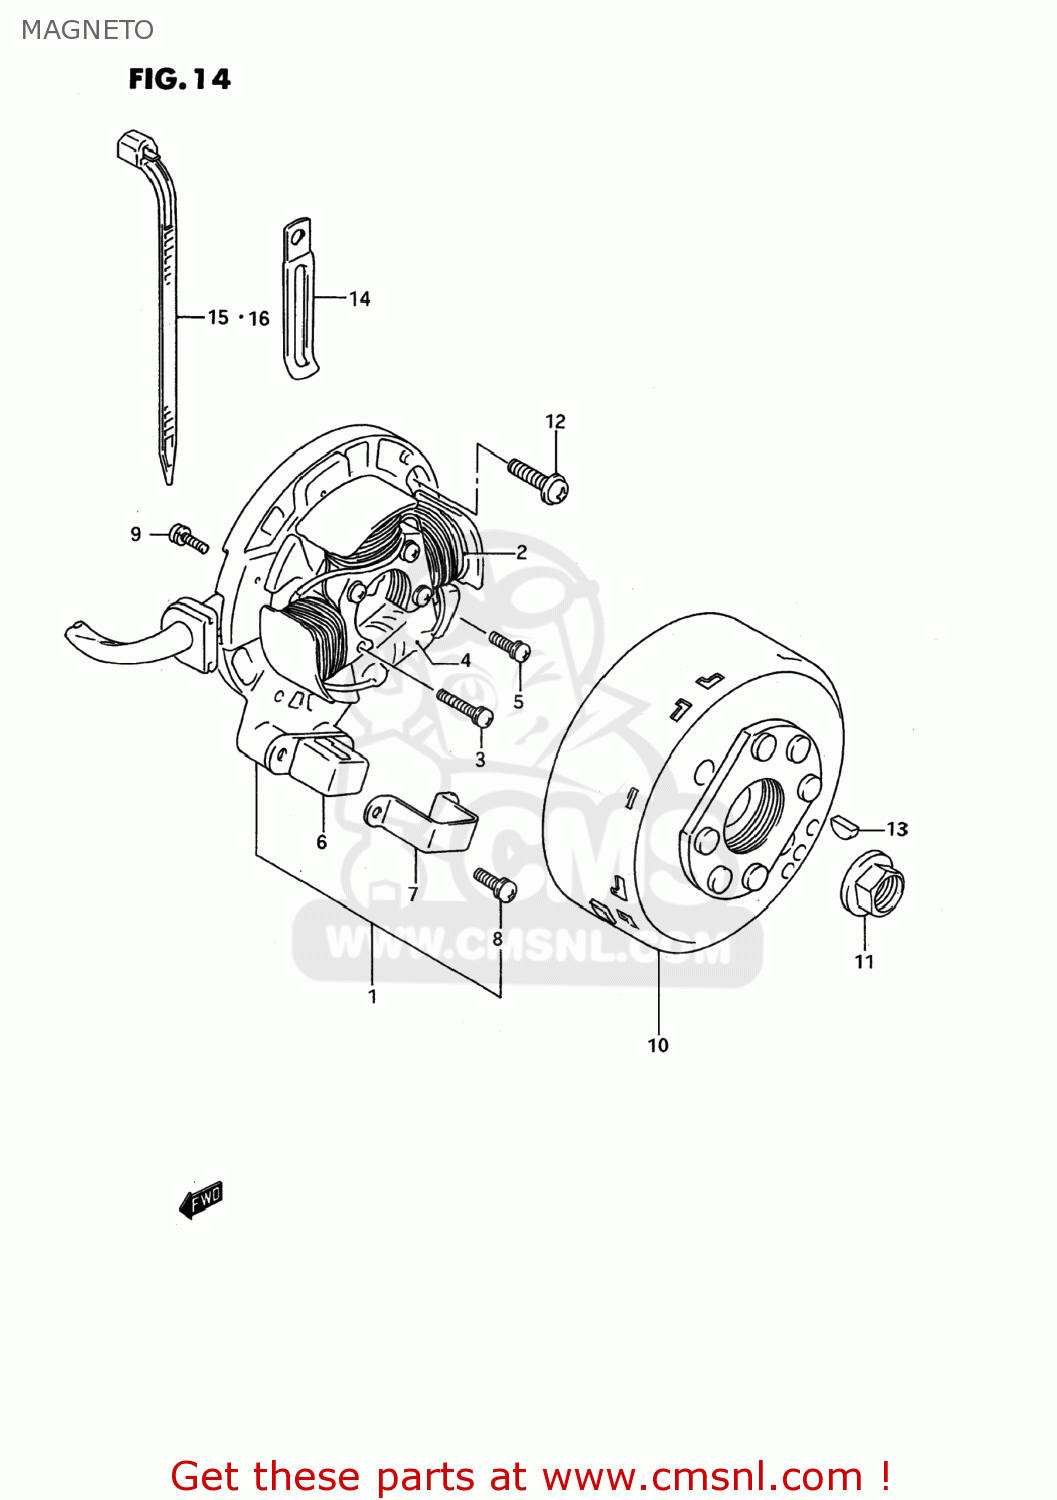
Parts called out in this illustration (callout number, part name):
1	STARTER ASSY
2	COIL,LIGHTING
3	SCREW
4	COIL,PRIMARY
5	SCREW
6	COIL,PULSER
7	HOLDER,P.U.COI
8	SCREW
9	SCREW
10	ROTOR ASSY
11	NUT
12	SCREW
13	KEY
14	CLAMP
15	CLAMP(L:125)
16	CLAMP(L:235)
